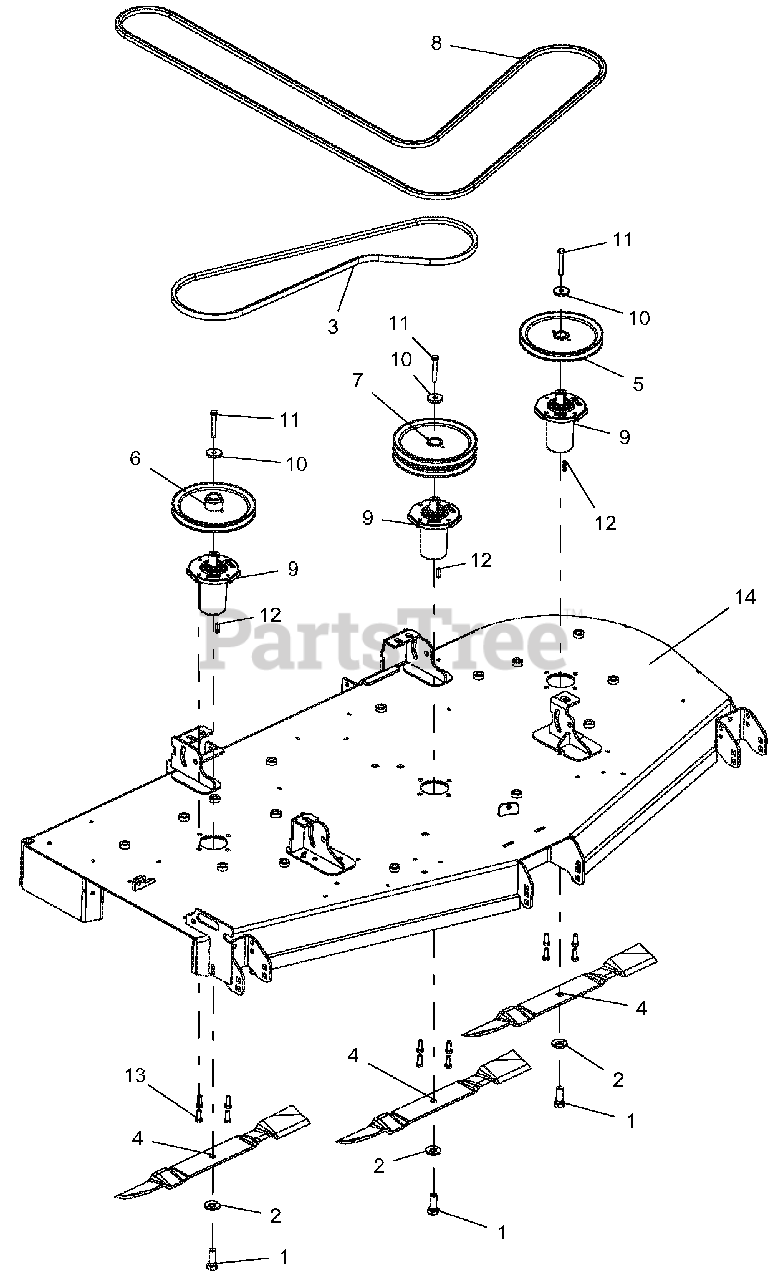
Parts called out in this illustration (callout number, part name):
1	BLT, HEX .62-18X1.75 GR8 YWZC
2	WSHR, BLVL .63X1.625X.14
3	V-BELT, B-COGGED
4	BLADE, MOWER -72" MULCH
5	SHEAVE-SINGLE 1.00" X 8.25" OD-BLACK
6	SHEAVE, SINGLE 1.00" ID X 8.25" OD-BLACK
7	SHEAVE-DOUBLE 1.00"ID X 8.25"OD-BLACK
8	HEX BELT, BB-WRAPED
9	SERVICE, ASM SPINDLE- DUCTILE
10	RETAINER, SHEAVE SPINDLE
11	BLT-HEX .38-16X2.75 GR8 YWZC
12	KEY-SQ .250X.250X1.00 RC 40-50
13	BLT-HEX .38-16X1.00 GR5 YWZC EP30
14	WLDMT, DECK 72-CE
